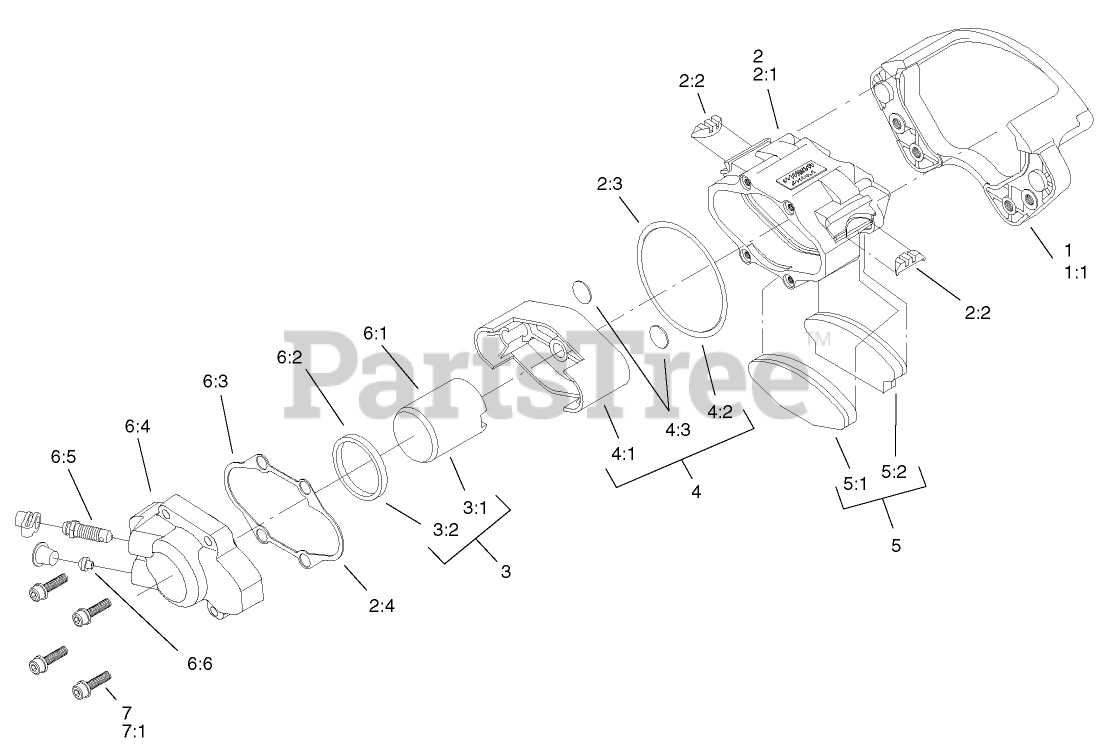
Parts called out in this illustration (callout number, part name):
1	BRACKET KIT
1:1	Bracket
2:1	Loose Parts Package
2:2	Loose Parts Package
2:3	Loose Parts Package
2:4	Gasket
3	PISTON & SEAL KIT
3:1	Loose Parts Package
3:2	Loose Parts Package
4:1	Loose Parts Package
4:2	Loose Parts Package
4:3	Loose Parts Package
5	PAD KIT
5:1	Loose Parts Package
5:2	Loose Parts Package
6	LH PISTON & COVER ASM KIT
6:1	Loose Parts Package
6:2	Loose Parts Package
6:3	Gasket
6:4	Cover
6:5	Loose Parts Package
6:6	Loose Parts Package
7	BOLT KIT
7:1	Loose Parts Package
